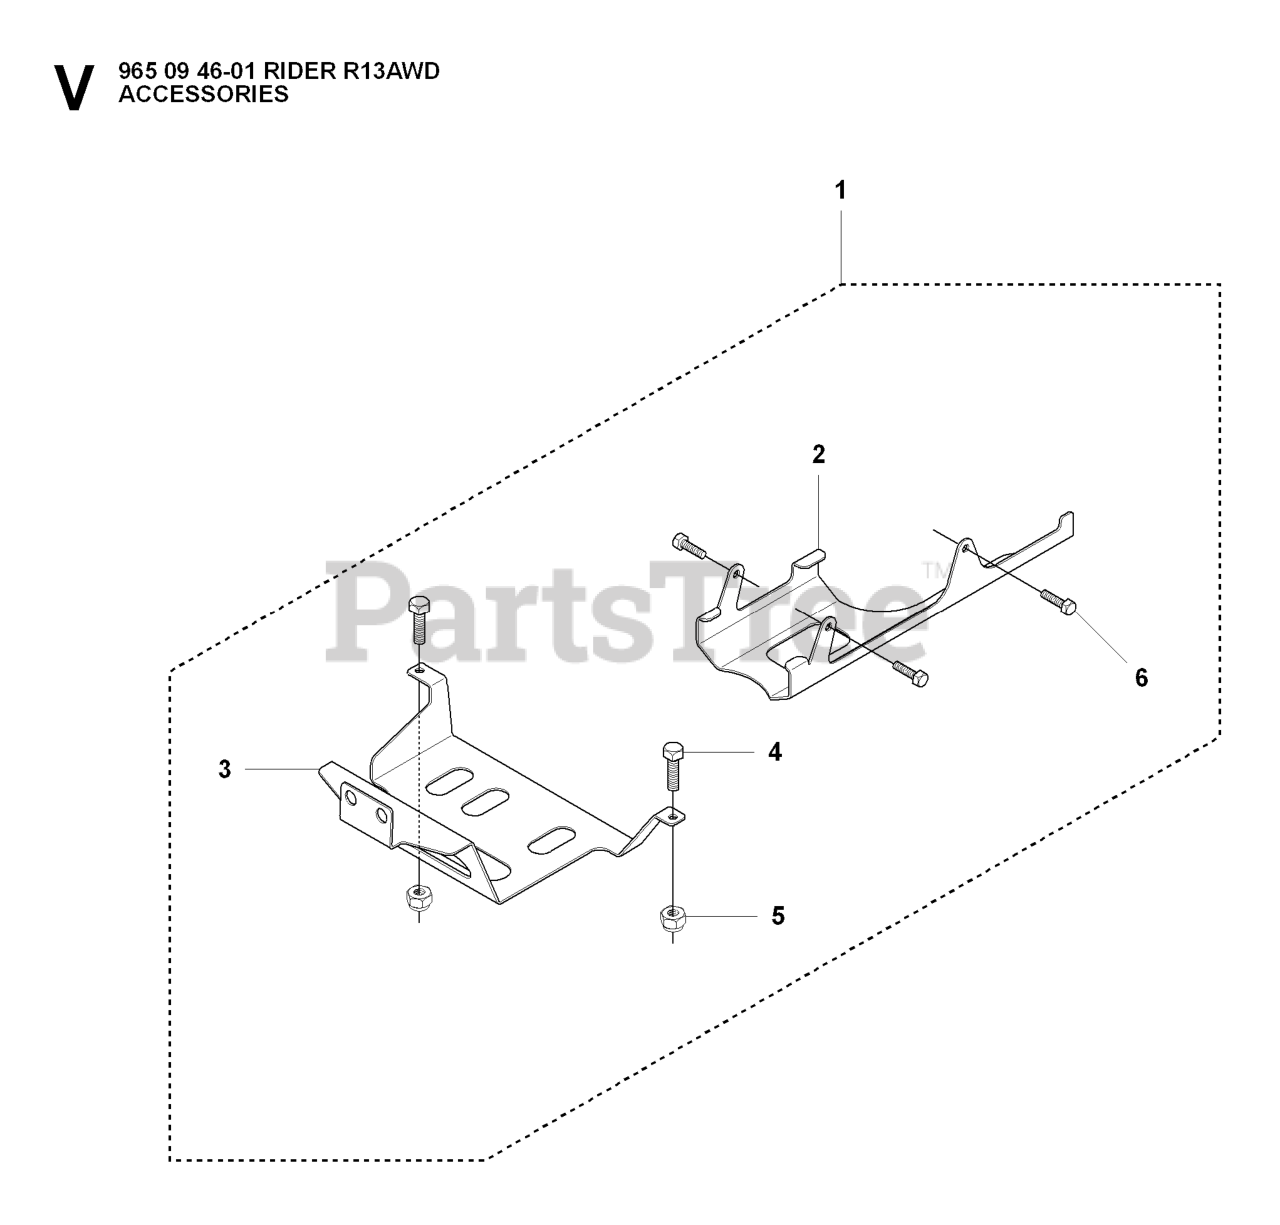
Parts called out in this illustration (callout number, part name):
1	AXLE PROTECTION KIT (R322T)
3	RP PROTECTION PLATE REAR
5	LOCKNUT M8
6	BOLT FLANGE - M8X16
